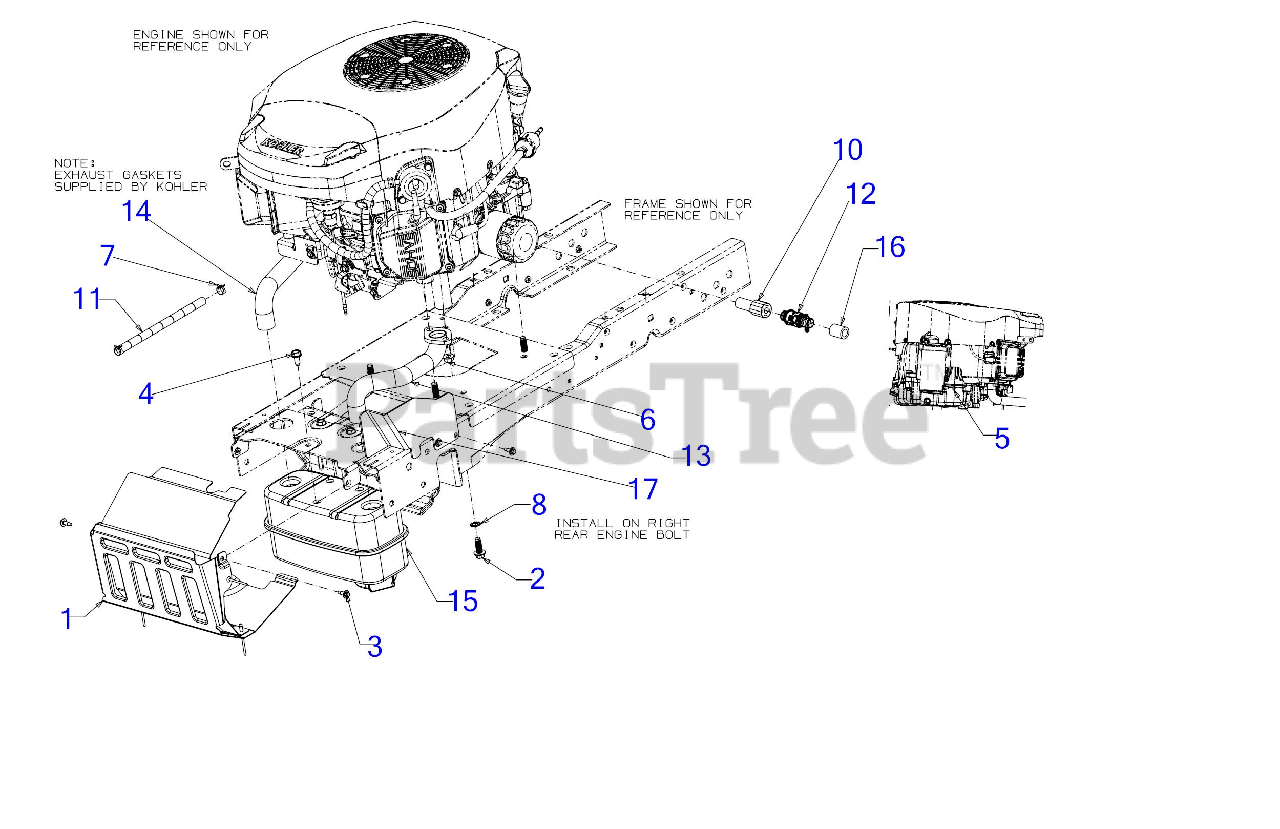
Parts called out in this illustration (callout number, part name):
1	MUFFLER SHIELD ASSEMBLY
2	SCREW 3/8-16 x 1
3	SCREW M6-1 x .625
4	SCREW M8-1.25 x .750
5	HEX NUT 1/4-20
6	HEX FLANGE NUT M8X
7	HOSE CLAMP 1/20
8	LOCK WASHER 3/8
10	OIL DRAIN FITTING 3/8-18 NPT (KH TWIN)
11	FUEL HOSE LOW PERMEATION
12	OIL DRAIN VALVE
13	EXHAUST PIPE (LH) (KOHLER)
14	EXHAUST PIPE (RH) (KOHLER)
15	EXHAUST MUFFLER (TWIN)
16	DRAIN HOSE 14''
